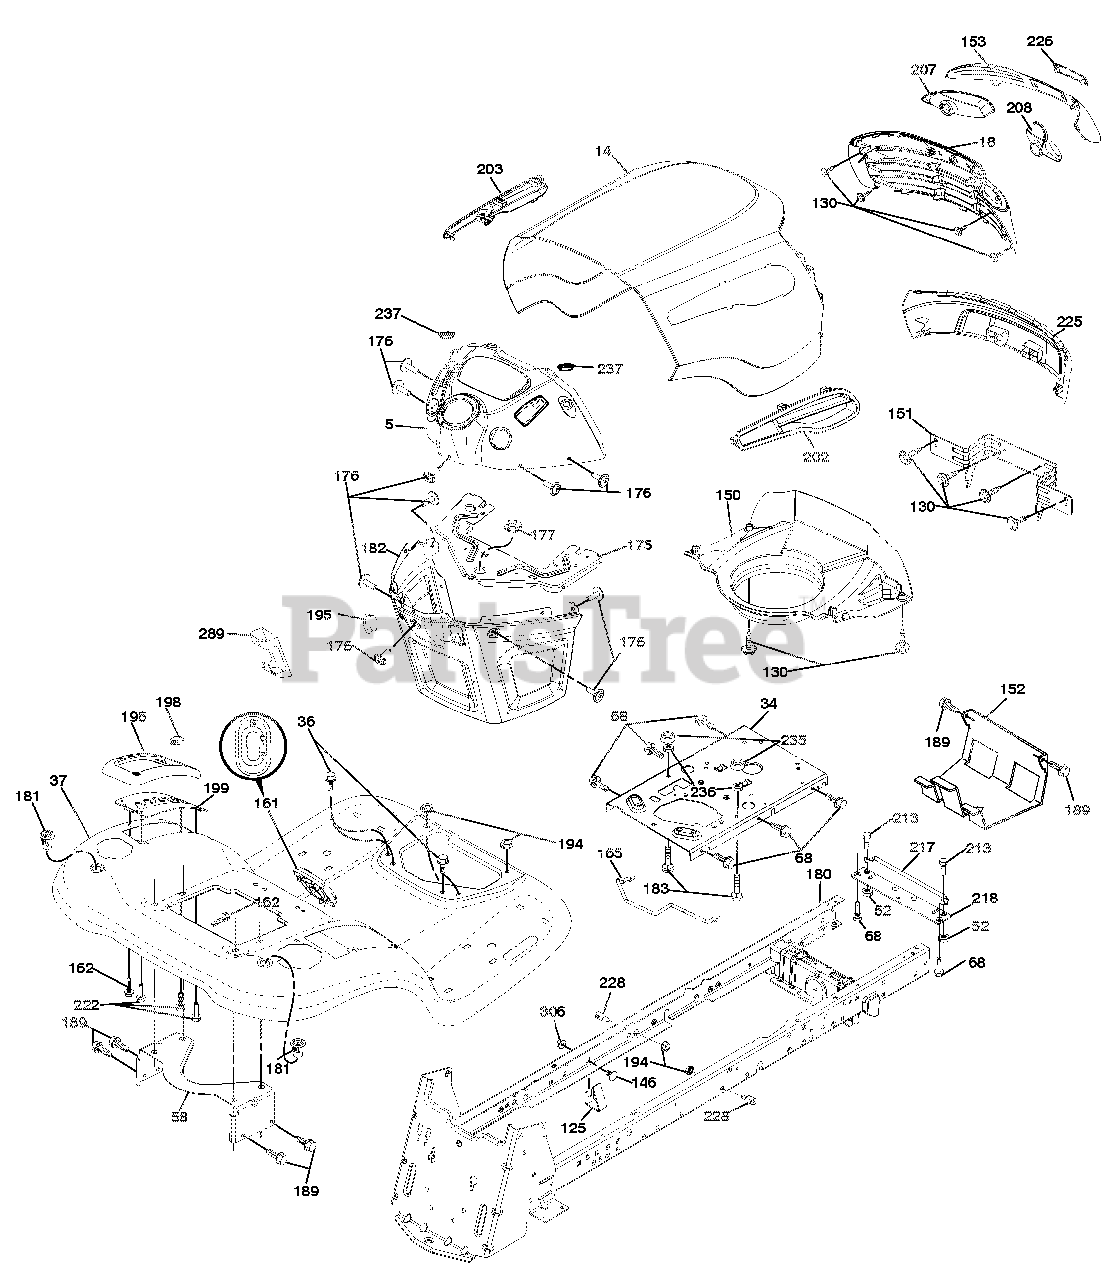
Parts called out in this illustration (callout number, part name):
5	DASH.P/L.TEX.CABLE
18	GRILLE.ELITE.ARIENS.BLACK
34	PLATE.ENGINE.WELDED.CHASSIS
36	SCREW.5/16-18X3/4.SMGML.TAP/R
52	Nut, Hex, Crownlock 5/16-18
58	FENDER SUPPORT BRACKET
68	SCREW.THDROL.5/16-18 X 1/2TYTT
125	CLIP.FUEL.LINE
150	AIR DUCT
151	BRACKET.PIVOT
152	SHIELD.BROWNING.W/TEX
153	LENS.BAR
161	CONSOLE FUEL WINDOW
162	SCREW.HEX.WSH.HI-LO.1/4X1/2UNC
165	SUPPORT.TANK.REAR.W/TEX
175	CROSSMEMBER.LT
176	SCREW.#10-24X5/8.RND.QUDRX.GIM
177	BUSHING.STEERING.YT/GT
180	CHASSIS
181	BUSHING MNT FEND CRGO BLK TEX
182	DASH.LOWER.LT.CCS
183	BOLT.FIN.HEX.5/16-18 UNC X1-1/
189	SCREW.5/16-18X3/4.SMGML.TAP/BL
194	Nut, Lock Hex Flange 5/16-18 u
195	PLUG HOLE DASH TOWER
196	CONSOLE ASM. DECK LIFT
198	INDICATOR DECK LIFT
199	PLATE DECK LIFT
202	VENT RH
203	VENT.SIDE.LH
207	BEZEL.LH
208	BEZEL.RH
213	BOLT.HEX.HD.1/4-20UNC X 3/4
217	ROD.PIVOT.HOOD
218	X-PIECE.HOOD.STOP.NON/STEALTH
222	SCREW.THD.ROLL.1/4-20 X 5/8
226	ARIENS.LOGO.PLATE
228	STUD.FASTNER.W/'D'ANTI-ROTATIO
235	SPACER.FENDER
236	NUT.CENTER LOCK.5/16-18 UNC
237	PLUG.MOUNT.CARGO
289	PLUG.CRUISE.CONTROL
306	Nut, Hex, Flangelock 3/8-16
